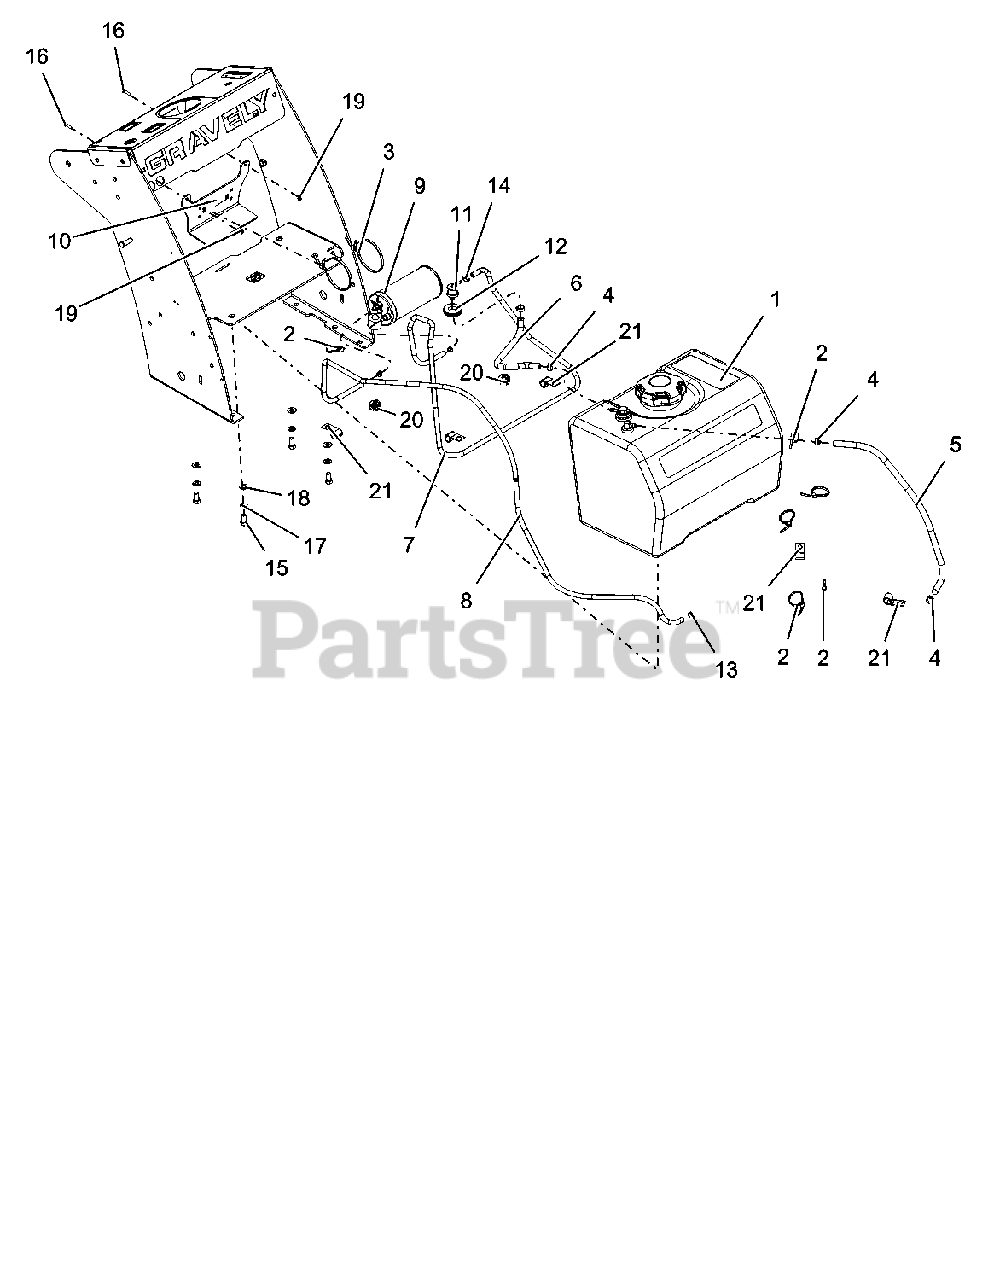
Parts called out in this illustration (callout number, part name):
1	TANK, FUEL LOW PERM
2	CABLE TIE, .15 X 8.50
3	CABLE TIE, .19 X 14.4
4	CLAMP, FUEL LINE
5	HOSE, FUEL 1/4 X 18.00
6	HOSE, FUEL HYDRO TANK - ROV
7	HOSE, FUEL HYDRO ROV - CC
8	HOSE, ACTIVE FUEL
9	400 CC CARBON CANISTER 3/16 PT
10	PLATE, CANISTER COVER LSCO HYD
11	VALVE, REMOTE ROLL OVER
12	GROMMET, REMOTE ROV
13	CLAMP - HOSE, SPRING .188
14	CLAMP, DBL PINCH 5/16" - 7/16"
15	BLT-HEX .38-16X.75 GR5 YWZC
16	@SCR-MCH 10-24X.75 HWH YWZC
17	WSHR-LK .38X.094 REG YWZC
18	WSHR-FL-STL.406X.812X.065 YWZ
19	NUT-KEPS 10-24
20	BUSH, PANEL SNAP .687X.875X.56
21	P-CLIP, .500 INSULATED
